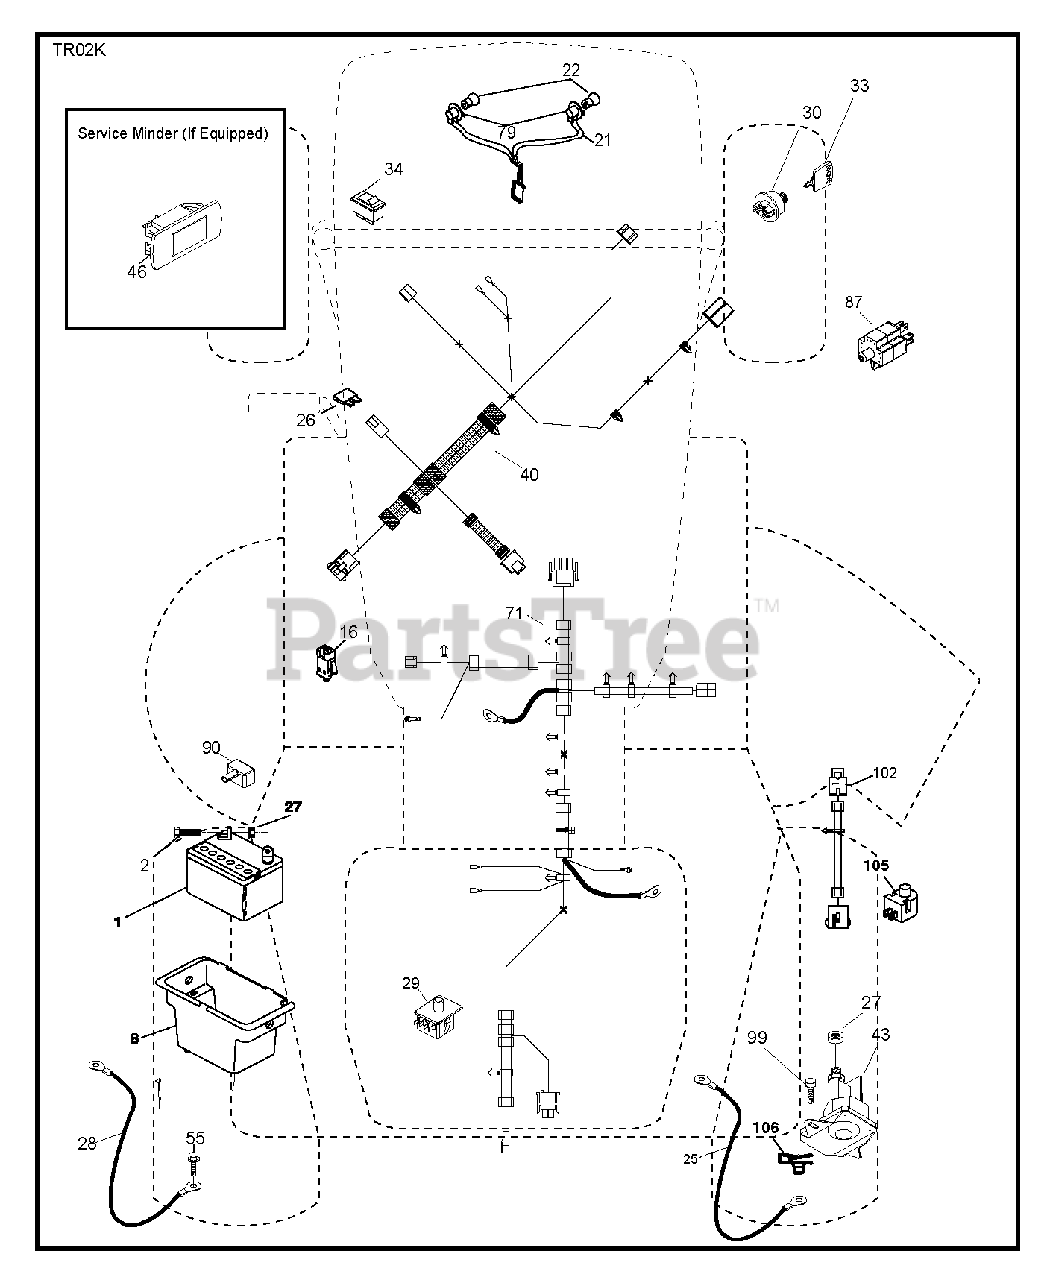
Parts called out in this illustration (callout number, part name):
1	REPL BY 532 12 38-99
2	BOLT.HEX.1/4.X.3/4.DICHROMATE
8	BOX.BATTERY.MNT.REAR.L
16	SWITCH INTERLOOK PUSH-IN
21	HARNESS.LIGHT W/4152J BULBS
22	LIGHTBULB
25	CABLE.BATT.RED.8GA.17
26	FUSE 20AMP
27	NUT
28	CABLE.GROUND.REAR.BATTERY.8G
29	SWITCH.SEAT.DP W/RAMPS
30	SWITCH.IGN.DELTA.W.LGH.ROS
33	KEY.CHAIN.BLISTER.PACK.GEN.USA
34	SWITCH LT
40	HARNESS.TEX.DASH.MAN.REAR BATT
43	SOLENOID.W/BRASS.PLUNGER
55	SCREW 5/16"
71	HARNESS.TEX.CHSSIS.REAR.BATT
79	BULB HOLDER ASM.
87	SWITCH.INTRLCK.CLUTCH.
90	COVER.TERMINAL.BATTERY
99	SCREW HEXWSHR 1/4-20X3/4
100	WASHER
102	HARNESS.PIGTAIL.VARIATOR.SD
105	REVERSE SWITCH
106	1/4-20 U NUT
